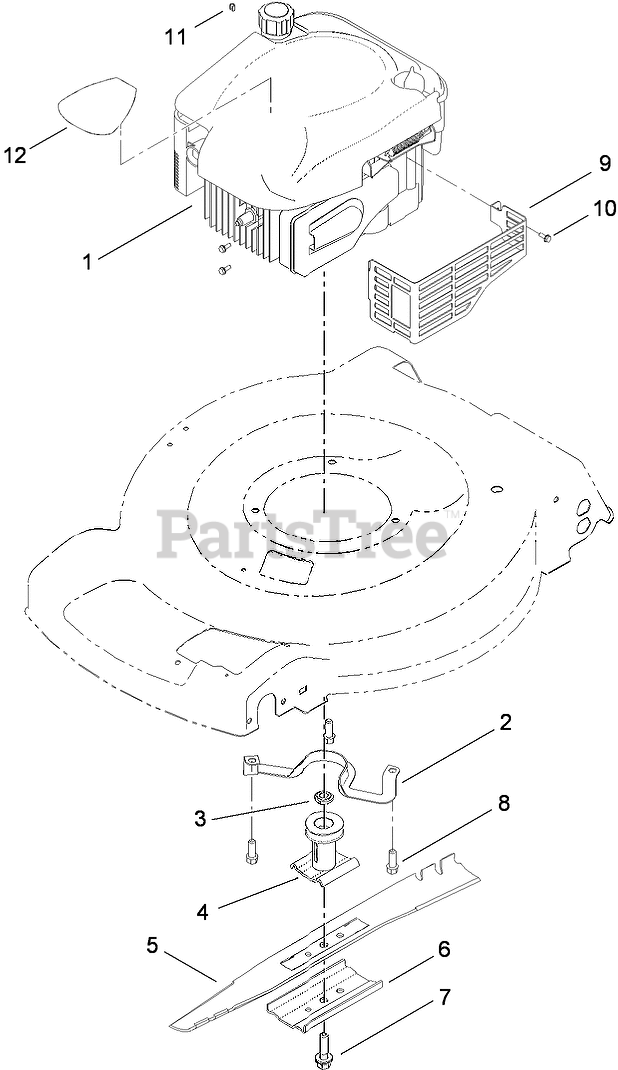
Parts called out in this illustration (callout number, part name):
2	Guide-Belt
3	Spacer-Driver
4	DRIVER-BLADE
5	BLADE-22 INCH
6	SUPPORT-BLADE
7	BOLT-BLADE
8	SCREW-TAPTITE
9	SHIELD-MUFFLER
10	SCREW-TAPTITE
11	STOP-ROPE
